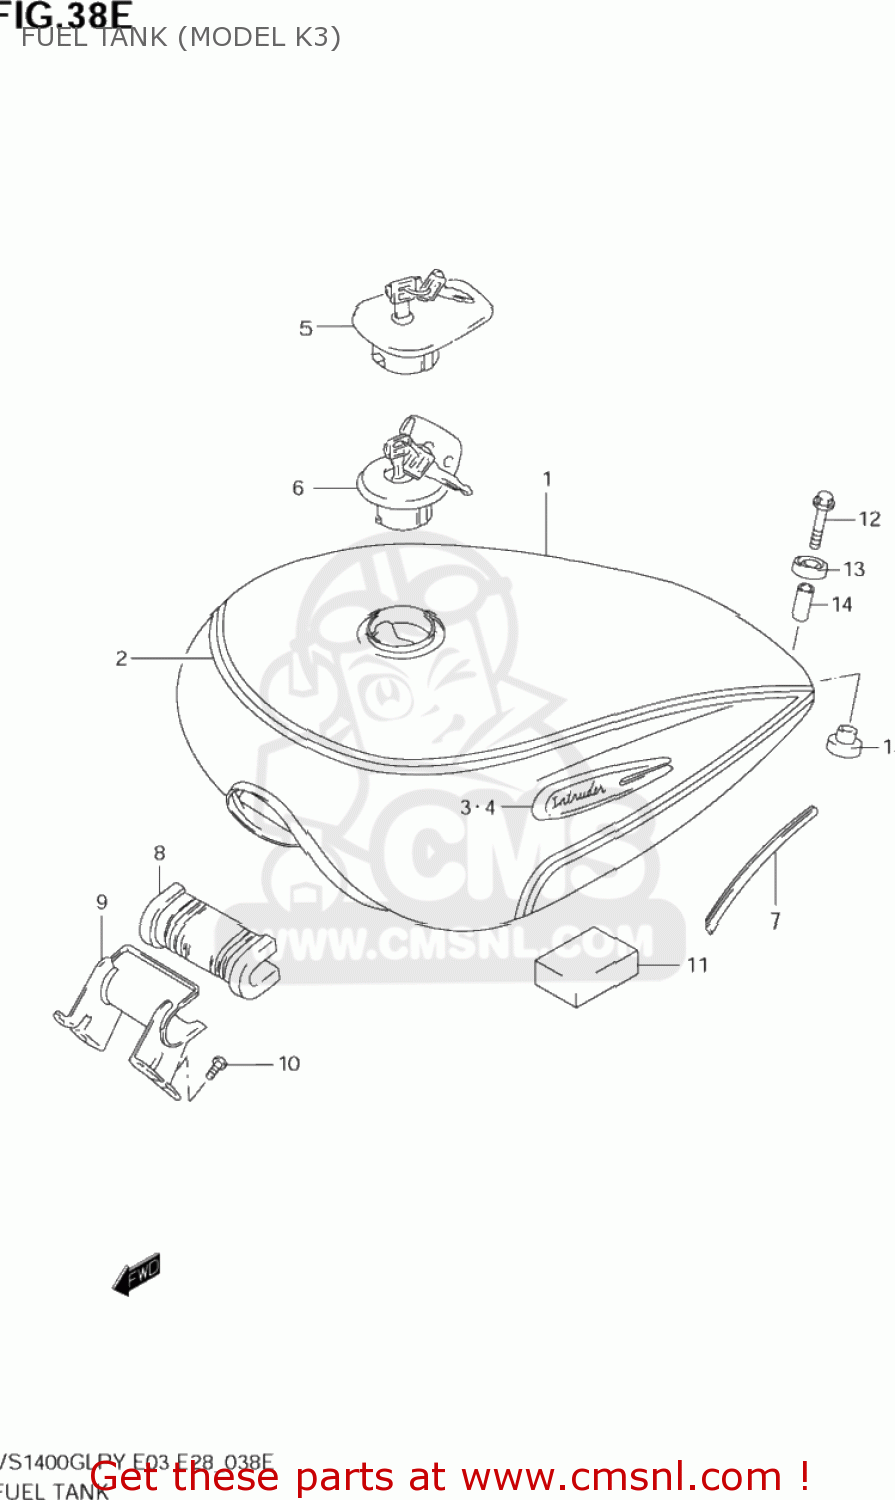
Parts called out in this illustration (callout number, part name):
1	TANK ASSY,FUEL
2	TAPE SET,FUEL TANK
3	EMBLEM,FUEL TANK,R
4	EMBLEM,FUEL TANK,L
5	CAP SET,FUEL TANK
6	CAP SET,FUEL TANK
7	MOLDING
8	CUSHION,FUEL TANK FR
9	BRACKET,FUEL TANK FR
10	SCREW
11	CUSHION
12	BOLT
13	CUSHION
14	SPACER(6.5X9X22.5)
15	CUSHION
